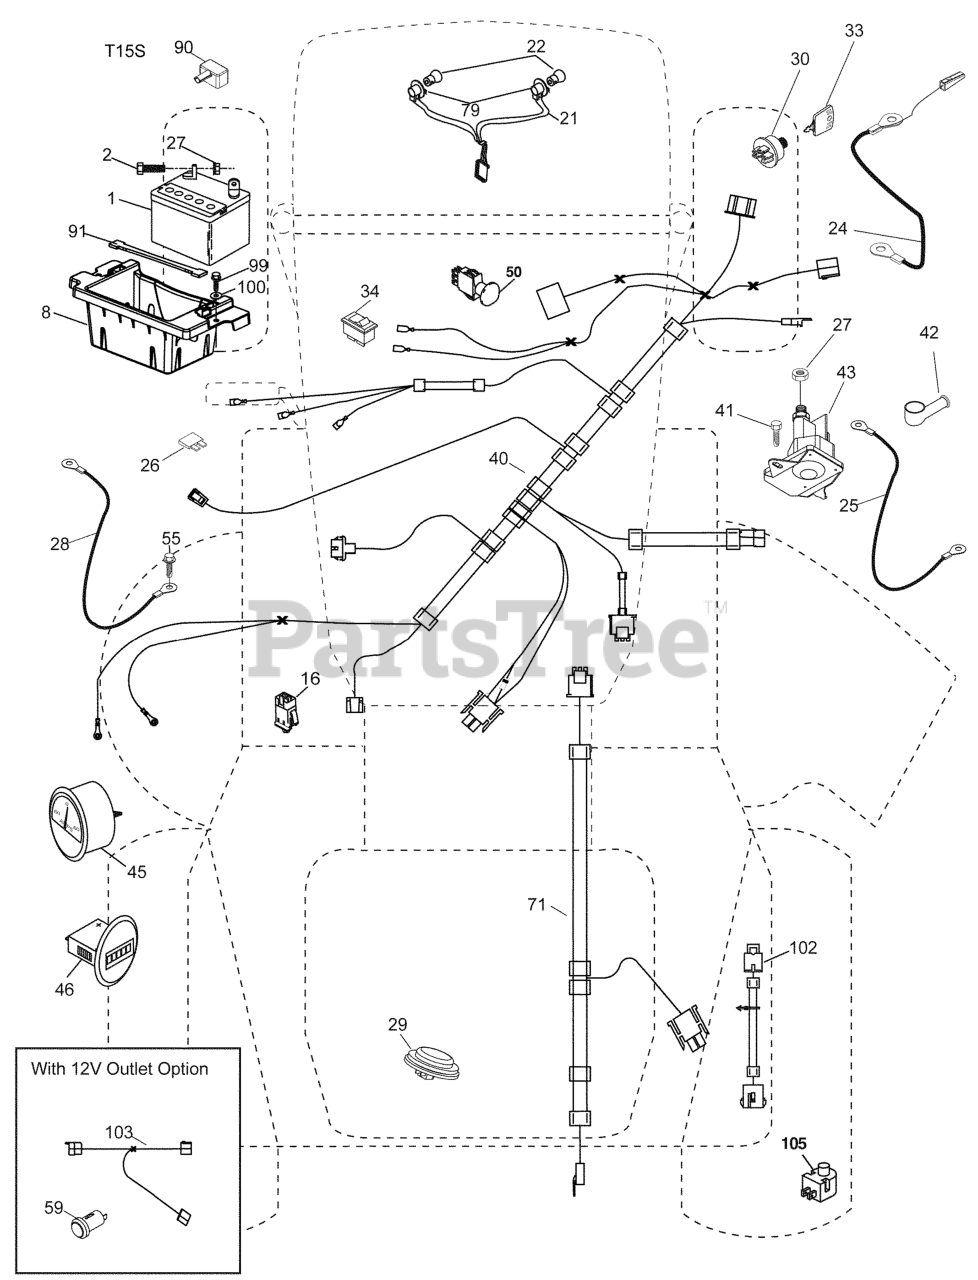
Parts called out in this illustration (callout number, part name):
1	Battery
2	BOLT.HEX.1/4.X.3/4.DICHROMATE
8	BOX BATTERY FULLY ASSEMBLED
16	SWITCH INTERLOOK PUSH-IN
21	HARNESS ASSY LIGHT
24	CABLE.BATT.POS.WIRE.TG.DA SOL
25	CABLE.STARTER.6G.BL/RED.17.5
26	FUSE 20AMP
27	NUT
28	CABLE GROUND 6 GA 21" 90T BLK
29	SWITCH.SEAT.DELTA.OPC.
30	SWITCH.IGN.DELTA.W.LGH.ROS
33	KEY.CHAIN.BLISTER.PACK.GEN.INT
40	HARNESS IGN. DASH
41	SCREW
42	TERMINAL COVER
43	SOLENOID.W/BRASS.PLUNGER
45	AMMETER GAUGE ROUND SNAP-IN
46	HOURMETER.GAUGE.RNK.SNAP.LS
50	RP.PTO.SWITCH.8 TERMINAL.BLACK
55	SCREW 5/16"
59	OUTLET.12-VOLT
71	HARNESS-CHASSIS SUB
79	BULB HOLDER ASM.
90	COVER.TERMINAL.BATTERY
91	STRAP.BATTERY.MOUNT.FRONT(2 2)
99	SCREW HEXWSHR 1/4-20X3/4
100	WASHER
101	PIGTAIL.MATNLK.NEW.HAR
102	HARNESS PIGTAIL PCH TEX ROS
103	HARNESS.PIGTAIL.12V.OUTLET.
105	REVERSE SWITCH
